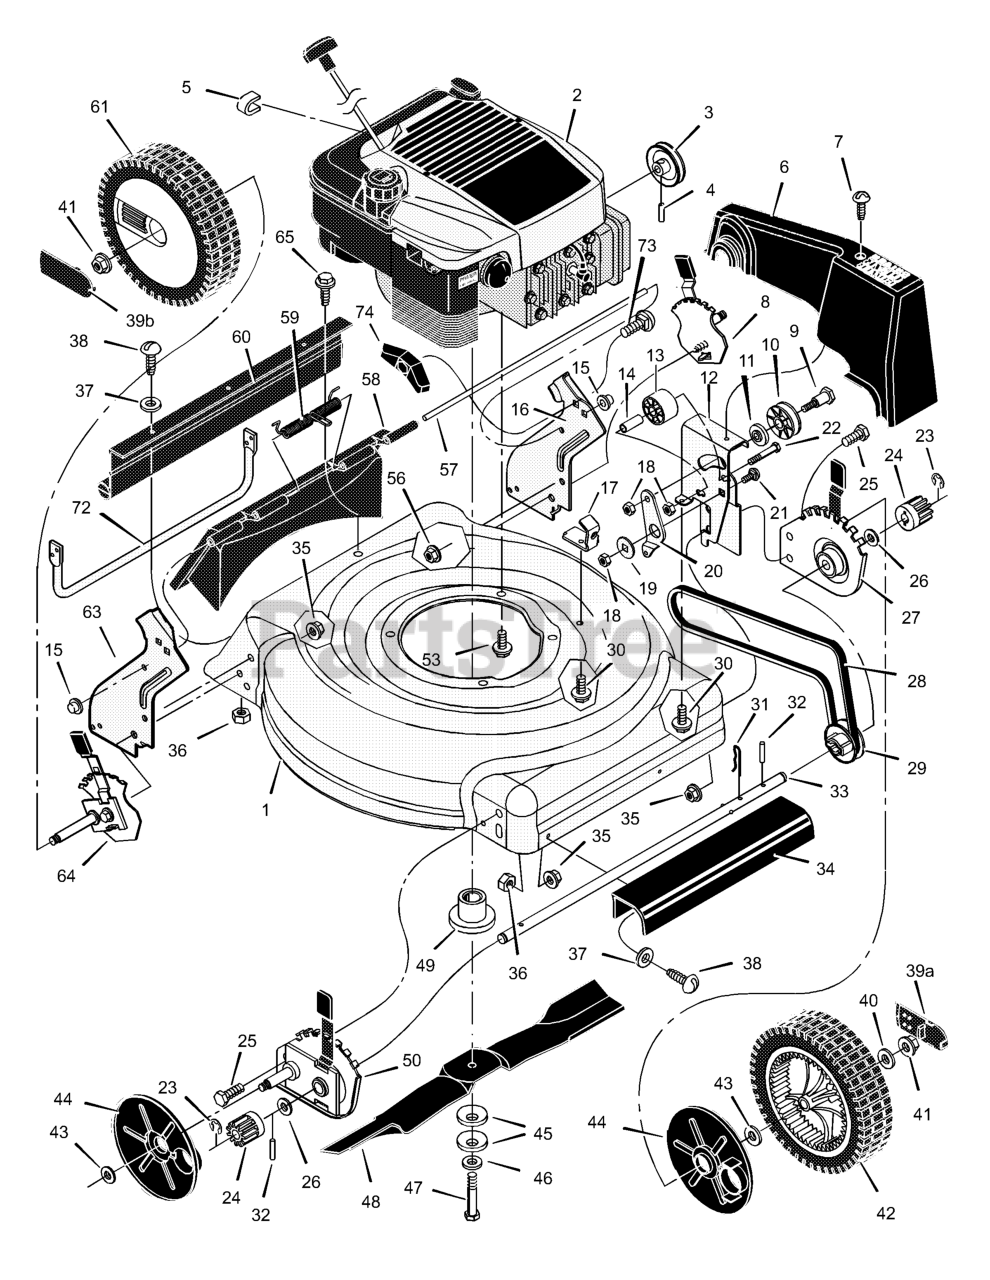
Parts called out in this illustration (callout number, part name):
1	Housing
2	Engine
3	Pulley, Engine
4	Pin, Spring
6	Cover, Belt (Gray)
8	Adjuster, Left Height
9	Bolt, Shoulder
12	Bracket, Idler Support
13	Pulley, Idler
14	Bearing
15	Nut, Push
16	Bracket, Left Handle
17	Bracket, Cable
18	Nut, Hex
20	Arm, Idler
21	Bolt, Carriage
22	Bolt, Shoulder
24	Gear, Pinion
25	Bolt
27	Adjuster, Left Frt. Height
29	Pulley, Axle
31	Pin, Hair
32	Pin, Spring
34	Cover, Axle (Gray)
35	Nut, Flange
36	Nut, Hex
39A	Cap, Hub
39B	Cap, Hub
40	Washer
41	Nut, Flange
42	Wheel, Drive
44	Cover, Dust
45	Washer, Belleville
49	Adapter, Blade
50	Adjuster, Right Frt. Height
53	Bolt, Engine
56	Nut, Flange
57	Rod, Pivot
58	Door, Rear (Gray)
60	Deflector, Rear
61	Wheel, Rear
63	Bracket, Right Handle
64	Adjuster, Right Height
72	Guard, Rear
73	Bolt, Carriage
